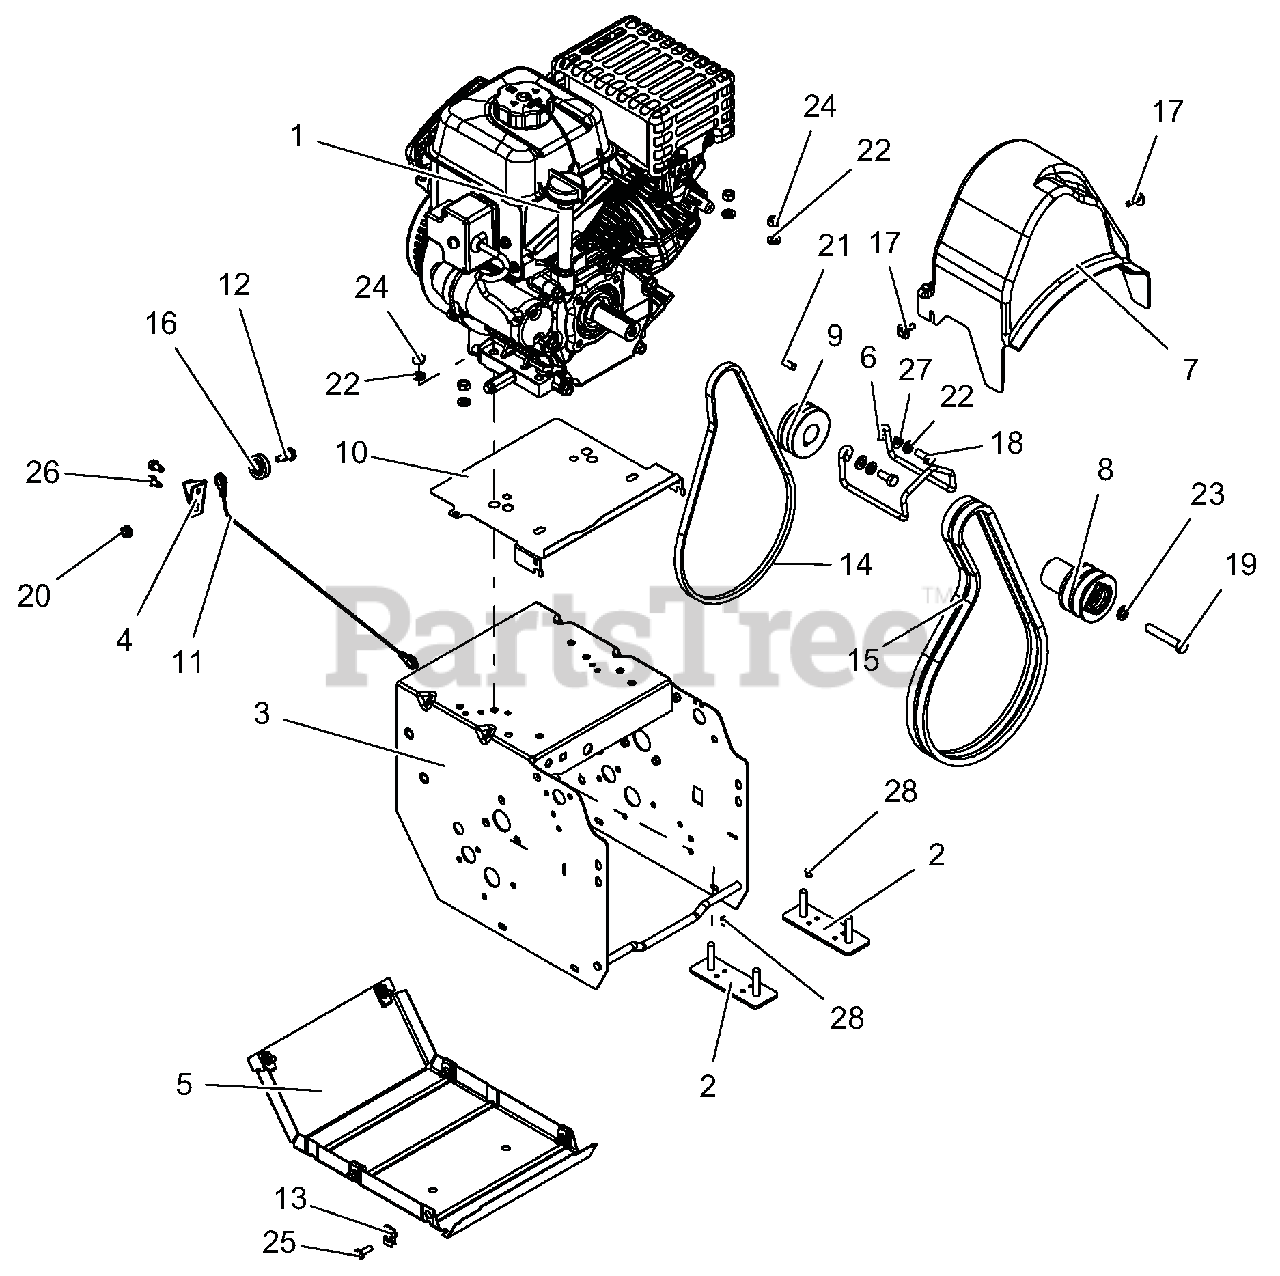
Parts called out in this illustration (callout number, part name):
1	ENGINE, ARIENS AX254 240V/60W
2	STRAP,ENGINE BOLT,ARIENS SML
3	WELDMENT, FRAME - DLX HYBRID
4	BRACKET, CABLE PULLEY
5	COVER, BOTTOM
6	FINGER, BELT
7	BELT COVER
8	SHEAVE,ATTACHMENT 2-GRV
9	SHEAVE DRIVE
10	BAFFLE,ENGINE,ARIENS SML BLOCK
11	CABLE, LOWER TRACTION (DELUXE)
12	BOLT, SHLDR-.375X.375X.25-20
13	NUT-RTNR .25-20X.56
14	V-BELT, 3L-WRAPPED
15	V-BELT, HA-RAW EDGE (SET)
16	PULLEY, CABLE
17	SCR-TAP .25-20X.5 CAPTIVE
18	BLT-HEX .31-24X.75 YWZC GR5
19	BLT-HEX .38-24X2.25 YWZC GR5
20	@NUT-LK-CTR-FLG .25-20 YWZC
21	KEY-SQ .25X.625X.25 SAE 8630
22	WSHR-LK .312X.097 HVY YWZC
23	@WSHR-LK .38X.094 REG YWZC
24	@NUT-HEX .31-18 YWZC
25	BLT-HEX .25-20X.75 HWH YZ GR5
26	SCR-TAP .25-20X.50 HWH TR YWZ
27	@WSHR-FL-STL.344X.688X.065YWZC
28	RVT-POP .187 YZ
